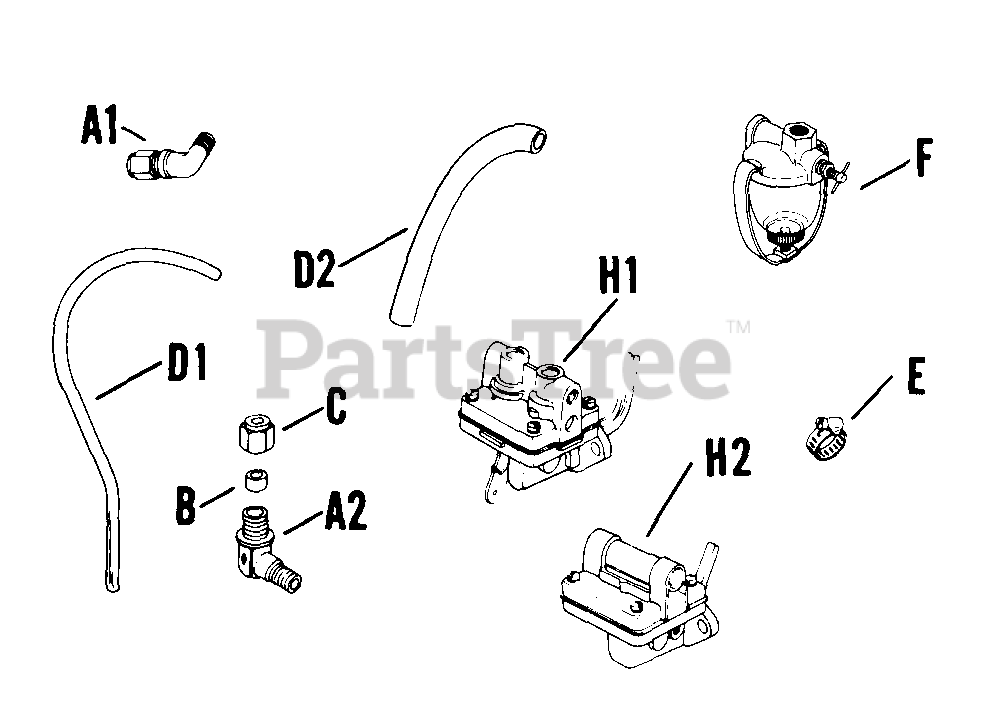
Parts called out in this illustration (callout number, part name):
A2	ELBOW - (#DSC)
D2	LINE - USE 25 353 01
E	CLAMP, HOSE 1/2" USE 25 237 14-S
F	KIT - USE 25 755 22
H1	KIT, FUEL PUMP USE 47 559 11-S
